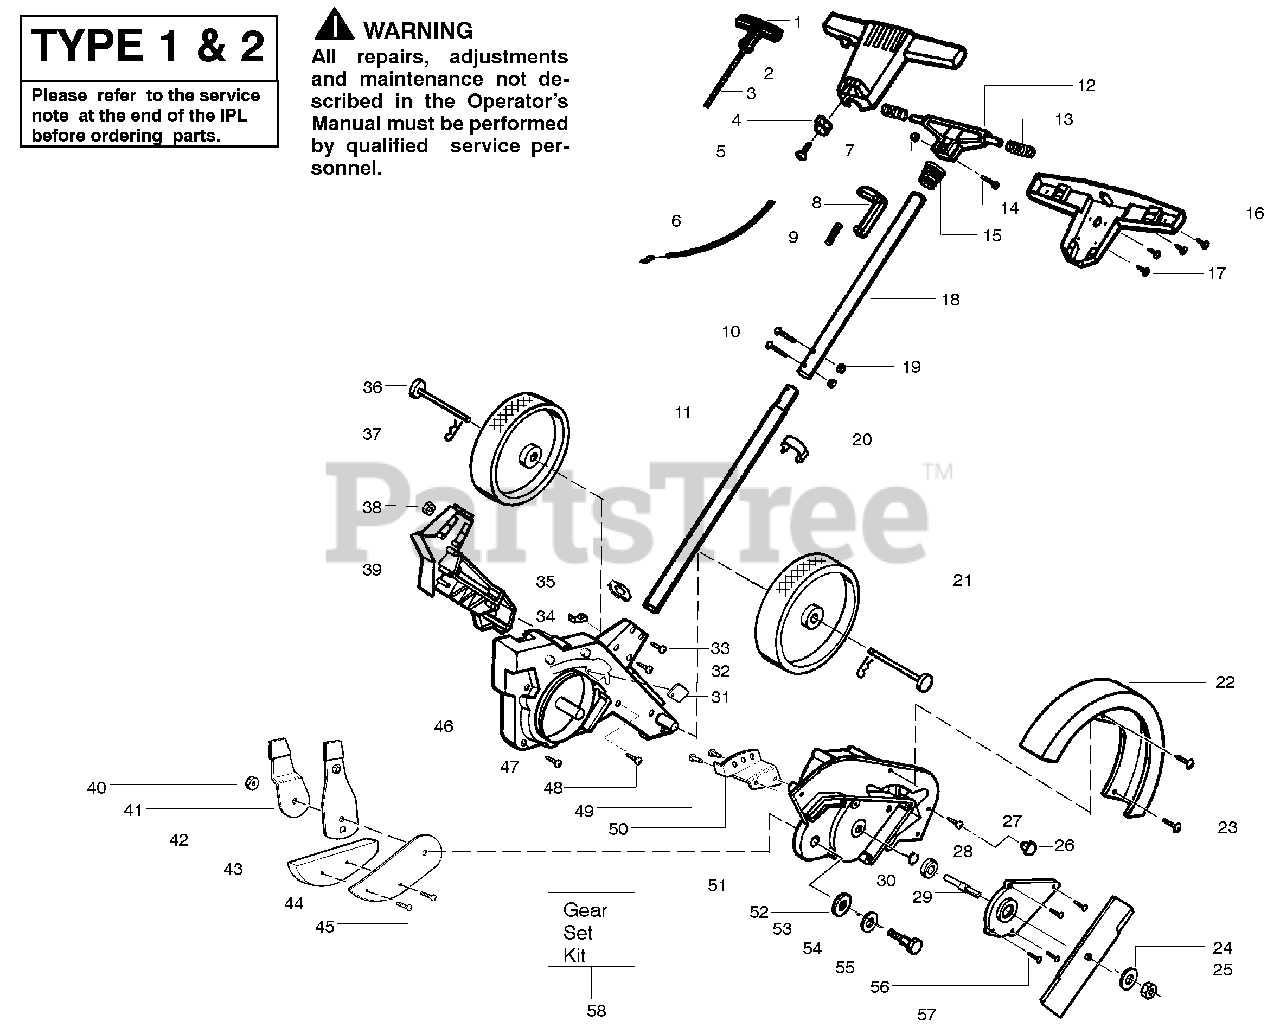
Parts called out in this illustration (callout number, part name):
1	Handle-Starter
2	Handle-Upper
3	Kit-Rope
4	Eyelet-Handle
6	Assy-Throttle Cable
8	Trigger-Throttle
9	Spring-Throttle
10	Bolt-Shoulder Tube
11	Tube-Lower Handle
12	Coupling-Handle
13	Spring-Isolator
15	Spring-Handle
16	Handle-Lower
18	Tube-Upper Handle
20	Clamp-Cable
21	Wheel-Rear
22	Shield-Front Blade
24	Washer-Belleville
26	Plug-Dust
28	Retainer Ring-Flat
29	Shaft-Output
30	Washer-Thrust
31	Retainer-Fuel Line
34	Nut-Speed
35	Gasket-Tube
36	Pin-Axle
37	Bridge-Pin
39	Cover-Axle
40	Nut-Swing Arm
41	Lever-Limiter
42	Assy-Lever Adjustment
43	Foot-Skid
44	Arm-Swing
46	Housing-Fan
50	Plate-Back
51	Assy-Gear Box
52	Washer-Bolt Adjust
53	Washer-Wave
54	Bolt-Shoulder
55	Assy-Bearing Holder
58	Kit-Gear Set
